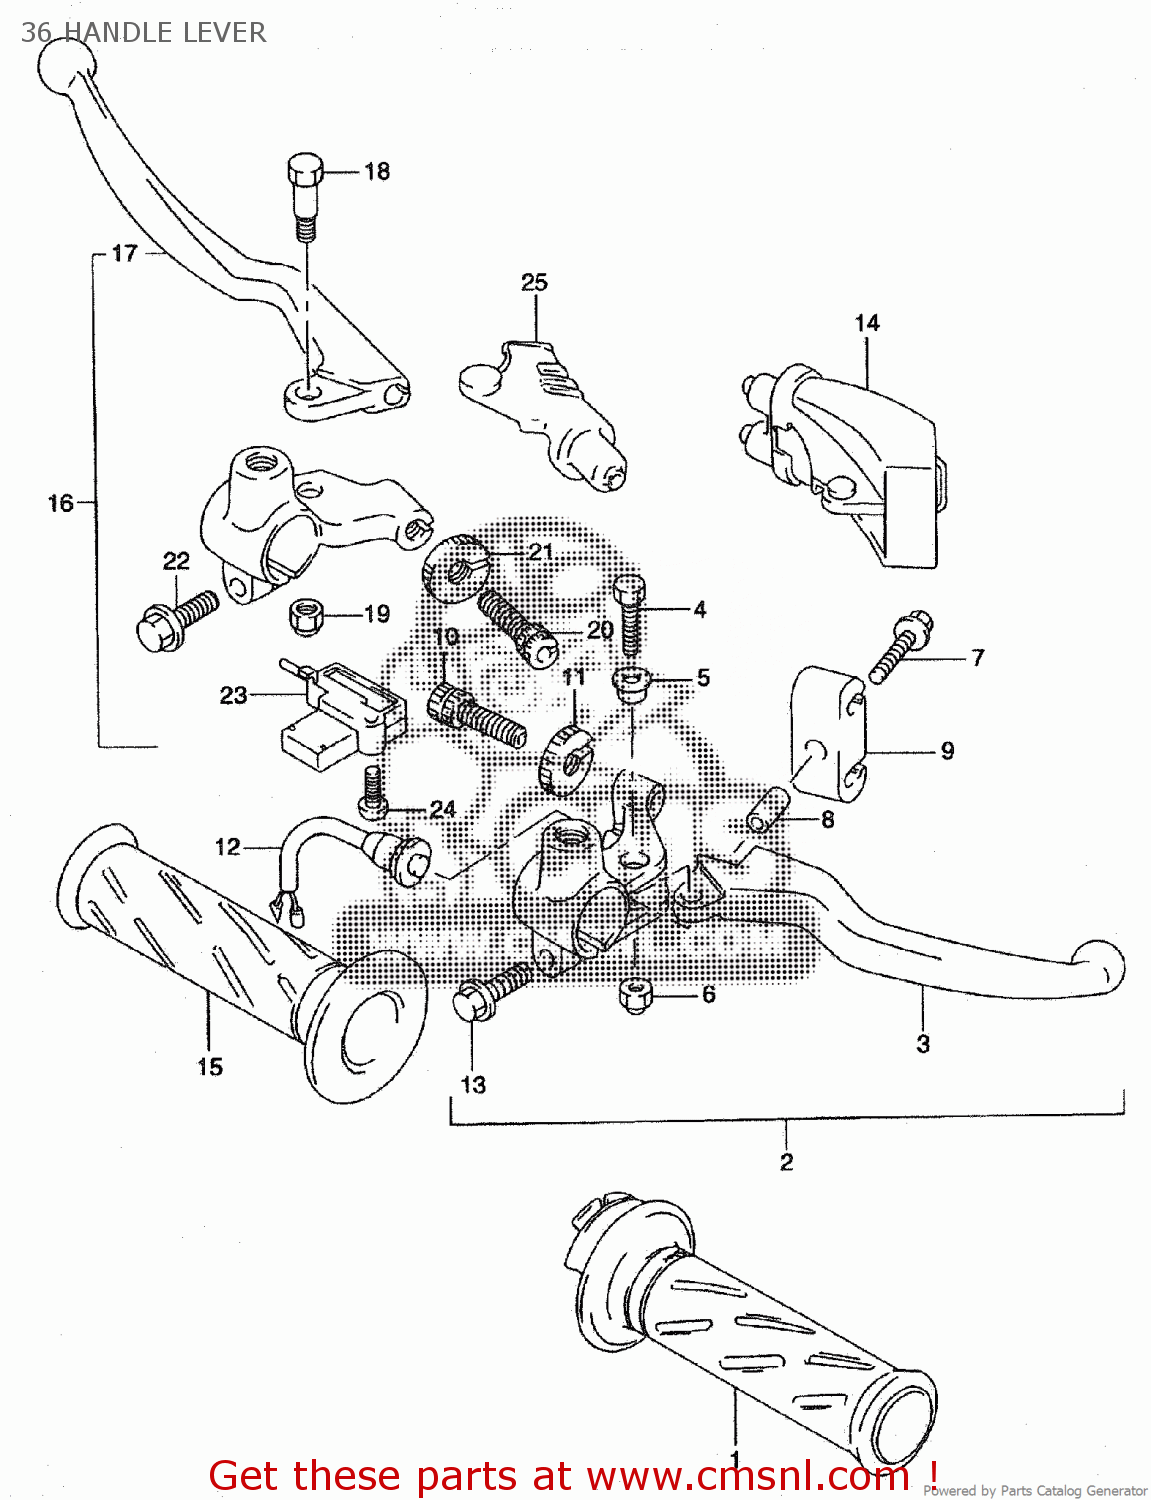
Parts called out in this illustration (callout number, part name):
1	GRIP,THROTTLE
2	LEVER ASSY,BRAKE
3	LEVER,BRAKE
5	SPACER,CLUTCH LEVER PIVOT
6	NUT
7	BOLT
8	SPACER,CLUTCH LEVER PIVOT
9	EQUALIZER
10	ADJUSTER,WIRE
11	NUT,LOCK
12	SWITCH ASSY,STOP
13	SCREW
15	GRIP,LEFT
16	LEVER ASSY,CLUTCH
17	LEVER,CLUTCH
18	BOLT,LEVER SET
19	NUT
20	ADJUSTER,WIRE
21	NUT,LOCK
22	SCREW
23	SWITCH,CLUTCH
24	SCREW
25	COVER,CLUTCH LEVER
